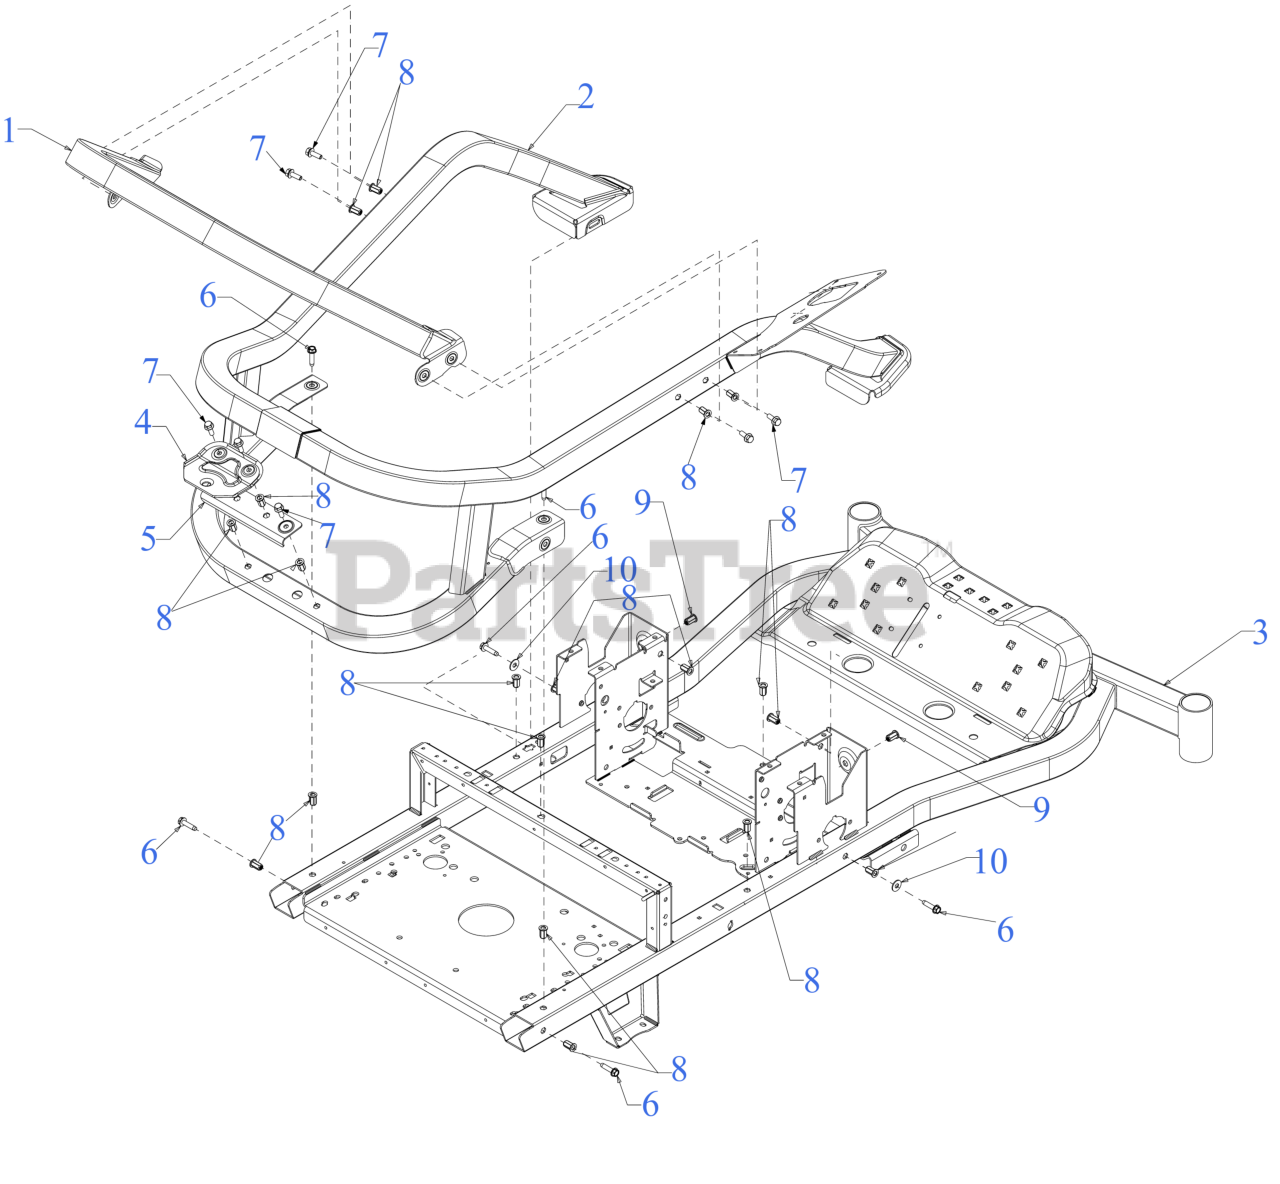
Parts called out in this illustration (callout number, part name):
1	UPPER FRAME HOOP
2	FRAME (UPPER)
3	FRAME (LOWER)
4	HITCH PLATE
5	HITCH MOUNT
6	SCREW 5/16-18 x 1.25
7	SCREW 5/16-18 x .875 GR5 HXFLG HD
8	NUT RIVET 5/16-18
9	NUT RIVET 5/16-18
10	FLAT WASHER
